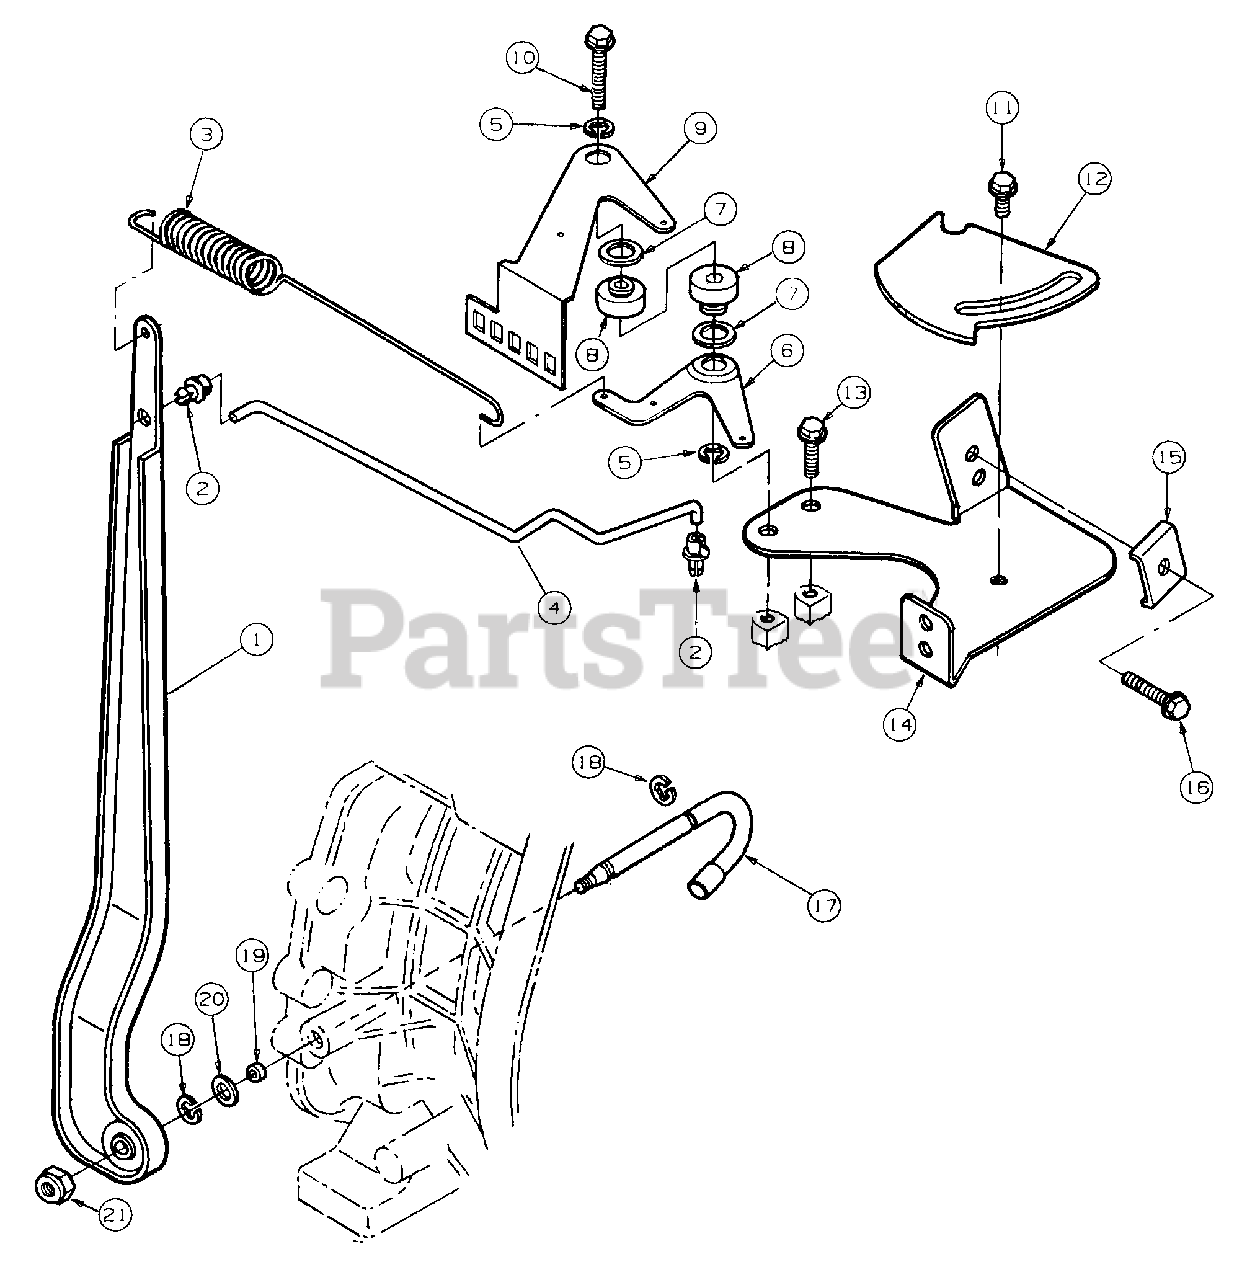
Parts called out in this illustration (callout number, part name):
1	Lever, Governor
3	Spring, Governor
4	Link, Throttle
6	Lever, Control
7	Washer, Wave Spring, M5
8	Pivot, Lever
10	Screw, Hex Flange M5 x 0.8 x 30 mm
11	Screw, Hex Flange M5 x 0.8 x 10 mm
12	Bracket, Throttle Stop
13	Screw, Hex Flange M5 x 0.8 x 16 mm
14	Bracket, Throttle Lever
16	Screw, Hex Washer Head, Thread Forming, #10-32 x 7/8
17	Shaft, Governor Lever
18	Clip, Retainer
19	Seal, Governor Shaft Lever
20	Washer, Flat, M8
21	Nut, Nylon Lock, M6 x 1
